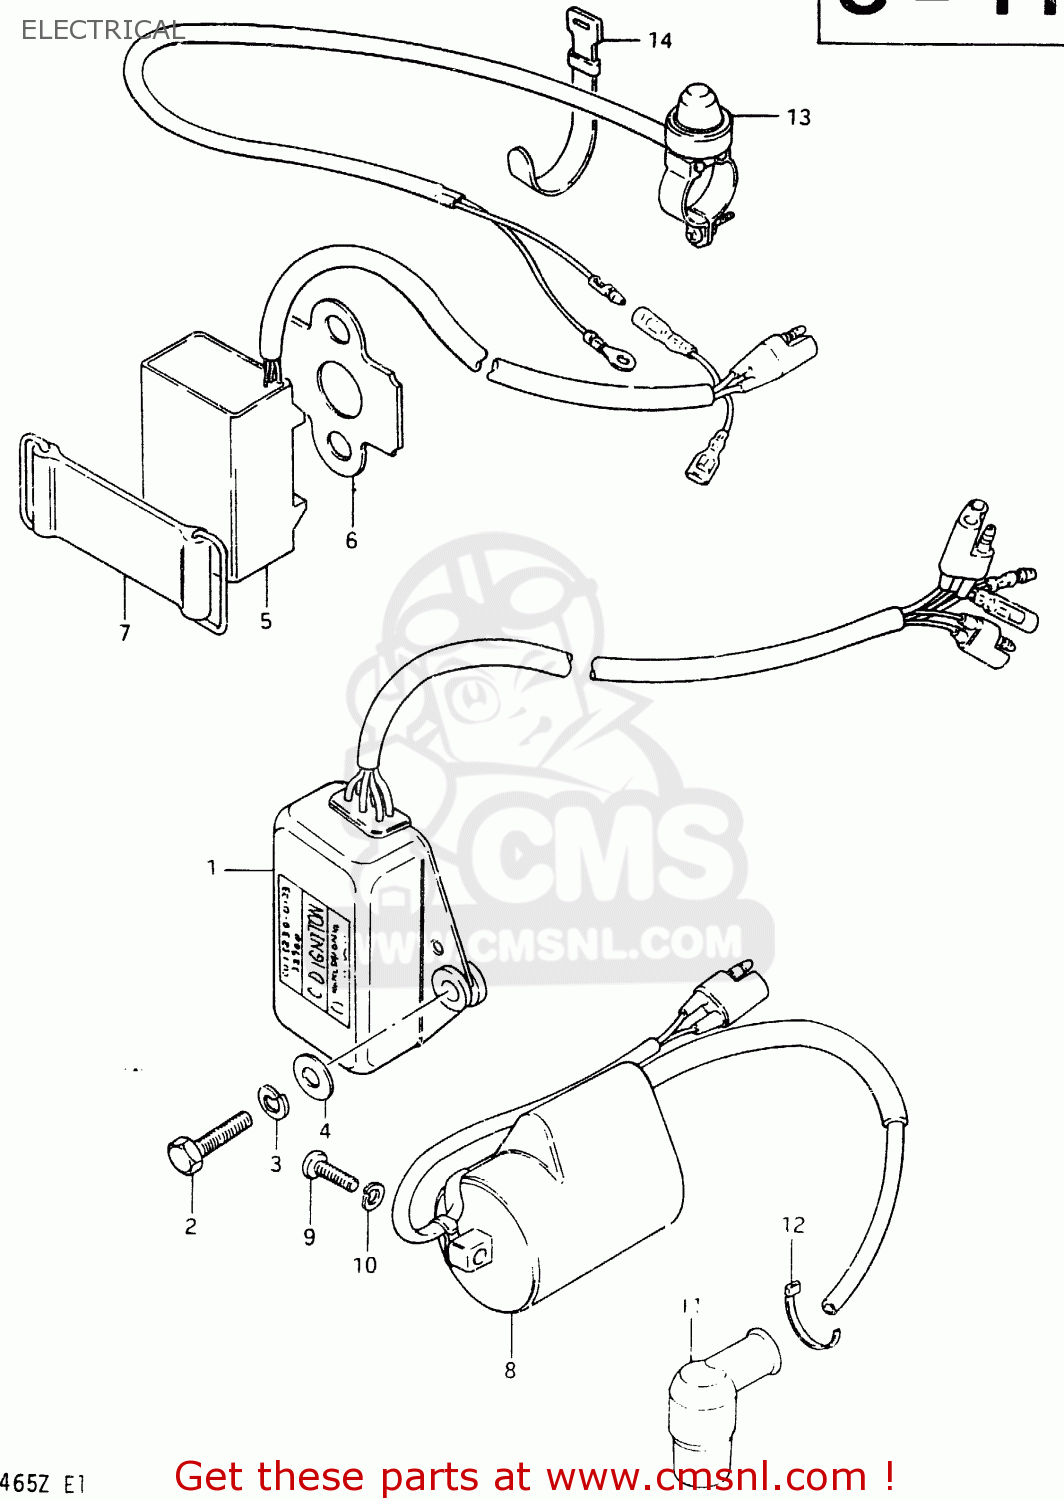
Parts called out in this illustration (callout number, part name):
1	CDI UNIT ASSEMBLY
2	BOLT
3	LOCK WASHER
4	WASHER(6.5X16X1.2)
5	CDI UNIT
6	PROTECTOR,CDI UNIT
7	BAND
8	COIL ASSY,IGNITION
9	SCREW 5X20
10	LOCK WASHER
11	CAP,SPARK PLUG
12	CLAMP
13	SWITCH ASSEMBLY
14	CLAMP(L:120)
